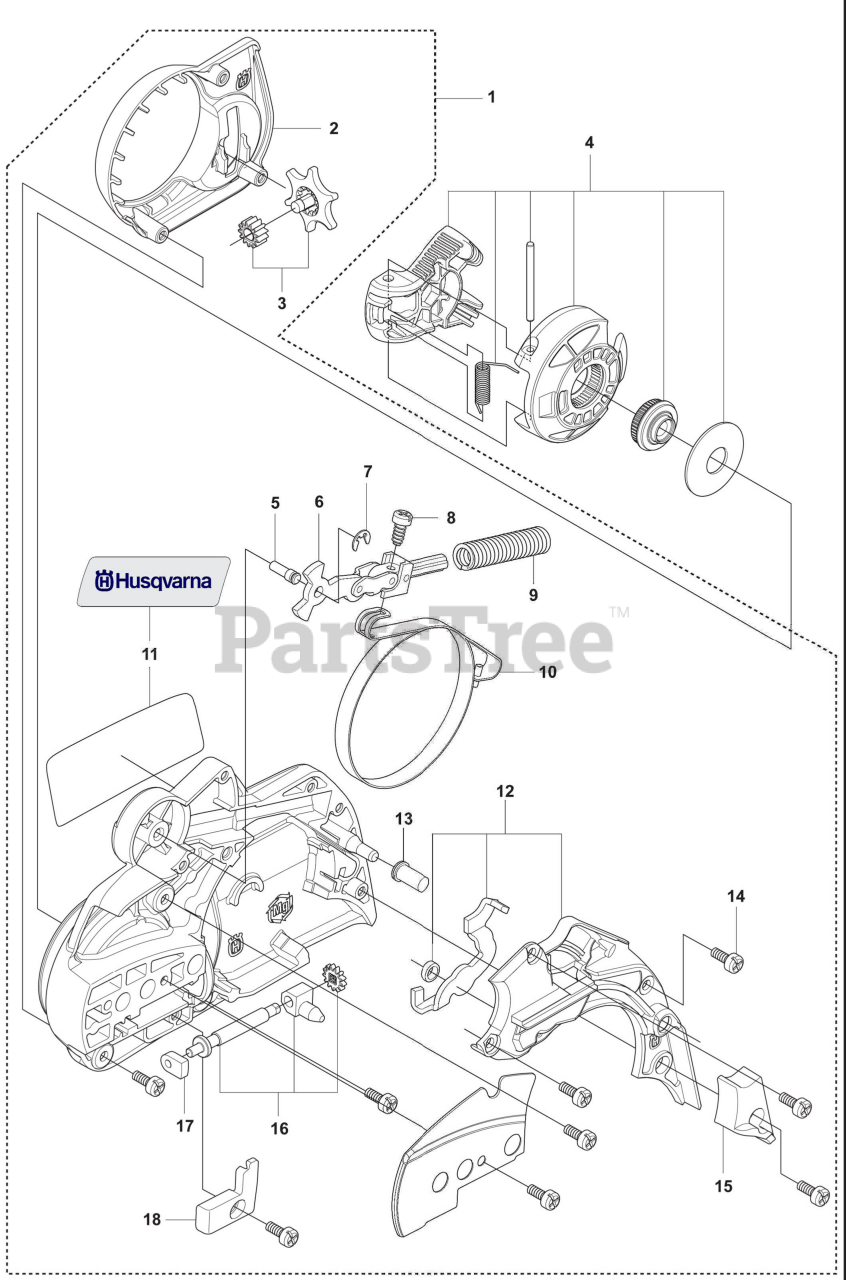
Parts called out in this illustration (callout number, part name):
1	CLUTCH COVER ASSY
2	Heat Shield
3	Chain Tensioner Wheel
4	Complete Knob
7	Bar Retainer
10	BRAKE BAND
11	Clutch Housing Decal
12	Cover Lid Assembly
15	Chain Wear Guard
16	Chain Tensioner Screw, Comp
17	Sleeve Bearing
18	Cover
